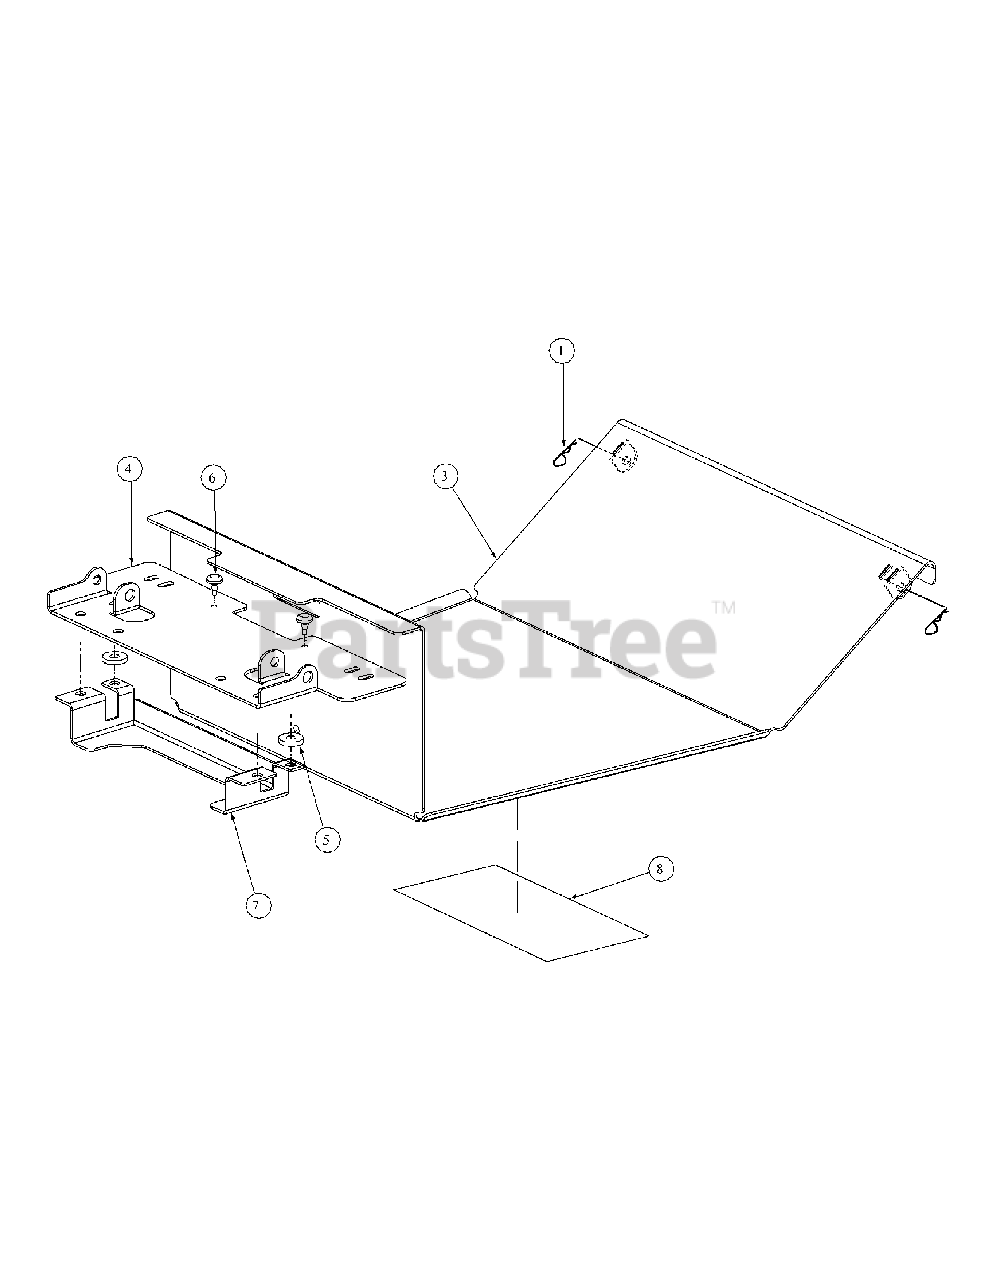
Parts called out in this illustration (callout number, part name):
1	Hair Pin, 3/8-1/2
3	Floor Panel Assembly
5	Washer
6	Rubber Bumper, .62 OD x .22 Thick
7	Support, Seat Bracket
8	Label, Belt Routing and Lubrication
